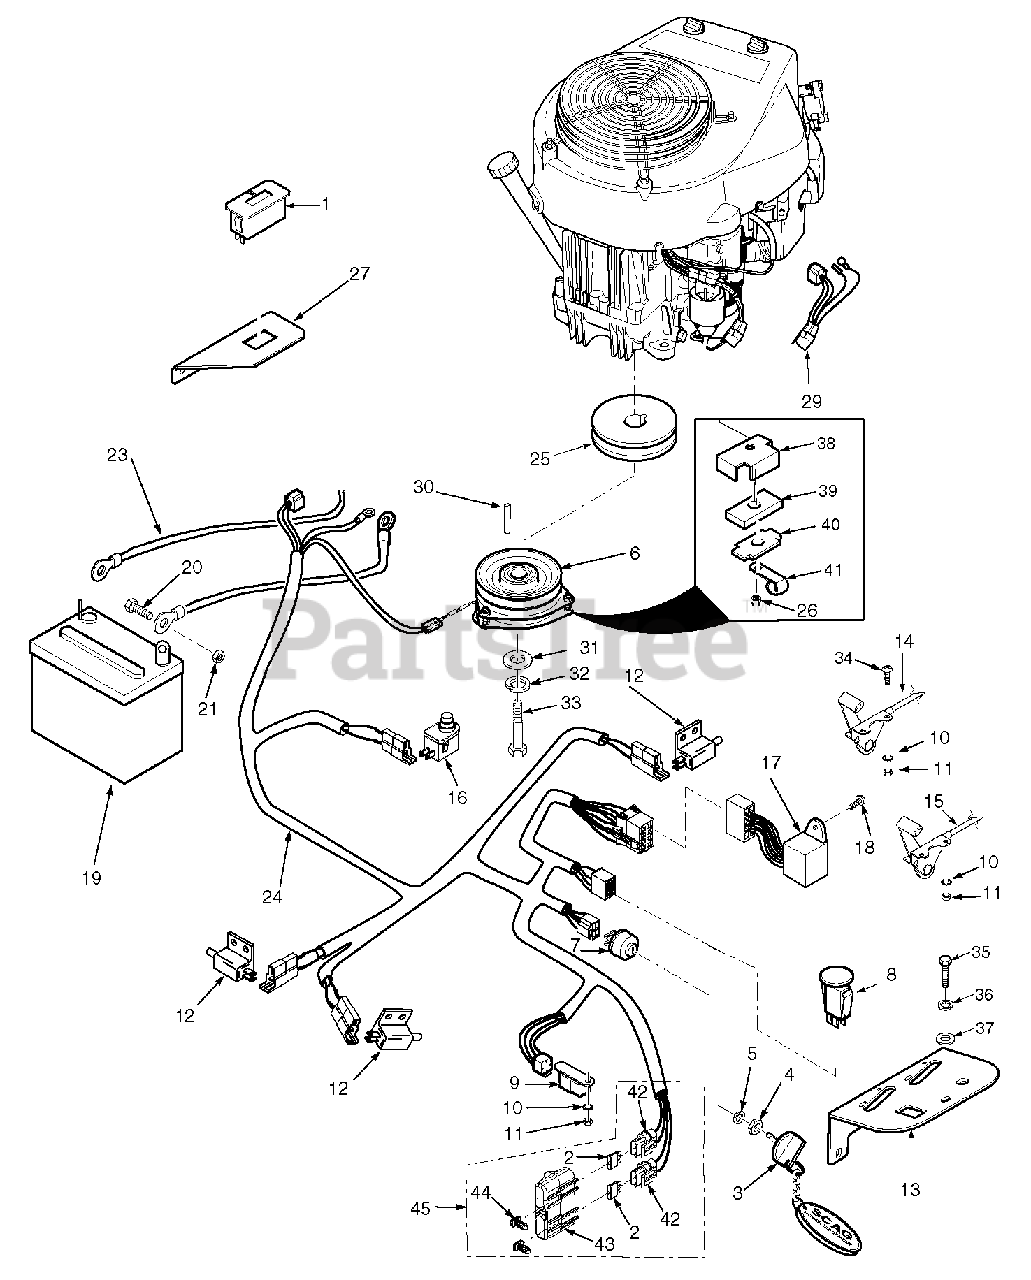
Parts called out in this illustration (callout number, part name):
1	Hourmeter
2	Fuse, 20 amp
3	Key, Ignition
3	Key Assembly w/Fob
4	Nut, Hex 5/8-32
5	Lockwasher, 5/8" Internal
6	Electric PTO Clutch GT3.5
7	Switch, Ignition
8	Switch, PTO
9	Relay
10	Lockwasher, #10 External Tooth
11	Nut, Hex #10-32
12	Switch, N/O
13	Panel, Instrument
14	Choke & Throttle Control - Kawasaki (Qty 2)
14	Choke Control - Kohler (Qty 1)
15	Throttle Control - Kohler (Qty 1)
16	Switch, Seat
17	Module, Interlock
18	Screw, #10-32 x .5" Phillips Head
19	Battery, 350CCA (Not Available Through Scag)
20	Bolt, Hex Head 1/4-20 x .5"
21	Nut, Hex 1/4-20
22	Cable, Battery Black (negative)
23	Cable, Battery Red (positive)
24	Wiring Harness, Main
25	Pulley, 5.45 OD x 1.125" Bore
26	Nut, Elastic Stop 5/16-18 Key
27	Mounting Bracket, Hour Meter
28	Screw, #10-32 x 1.5" Phillips Head
29	Adapter, Wiring Harness (Briggs & Stratton only)
29	Adapter, Wiring Harness (Kawasaki only)
29	Adapter, Wiring Harness (Kohler only)
30	Key, 1/4 x 1/4 x 3-1/4"
31	Flatwasher, 7/16-.469 x 1-3/4" x 1/4"
32	Lockwasher, 7/16"
33	Bolt, Hex Head 7/16-20 x 2-1/2" UNF
34	Screw, #10-32 x 3/4"
35	Bolt, Hex Head 5/16-18 x 3/4"
36	Lockwasher, 5/16"
37	Flatwasher, 5/16-.375 x .875 x .083
38	Backing Plate
39	Rubber Pad, Clutch Stop
40	Plate, Backing
42	Fuse Holder
43	Cover, Sealed Double
44	Clip, Wire
45	Double Fuse Assembly, Sealed
